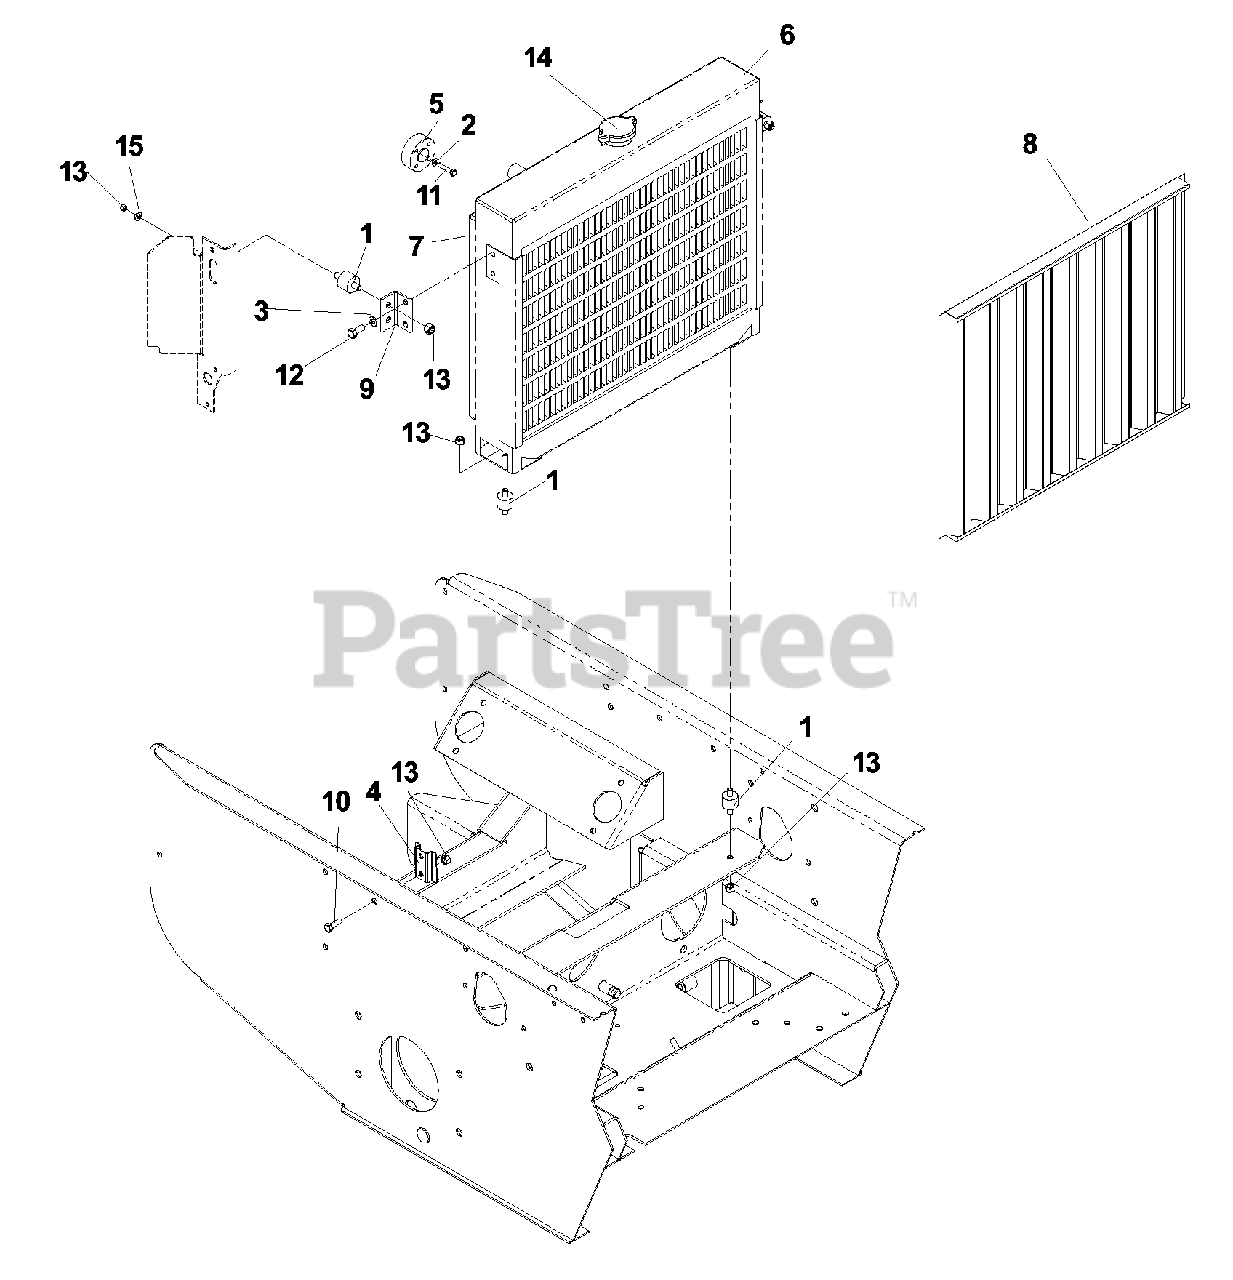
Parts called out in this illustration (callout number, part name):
2	Lockwasher, 1/4
3	Lockwasher, 5/16
4	Bracket, mounting
5	Spacer, fan
8	Debris guard
9	Bracket, isolator
10	Bolt, 5/16-18 x 1
11	Bolt, M6-1 x 30
12	Bolt, 5/16-18 x 3/4
13	Nut, 5/16-18
14	Cap, radiator
15	Washer, 5/16, SAE
